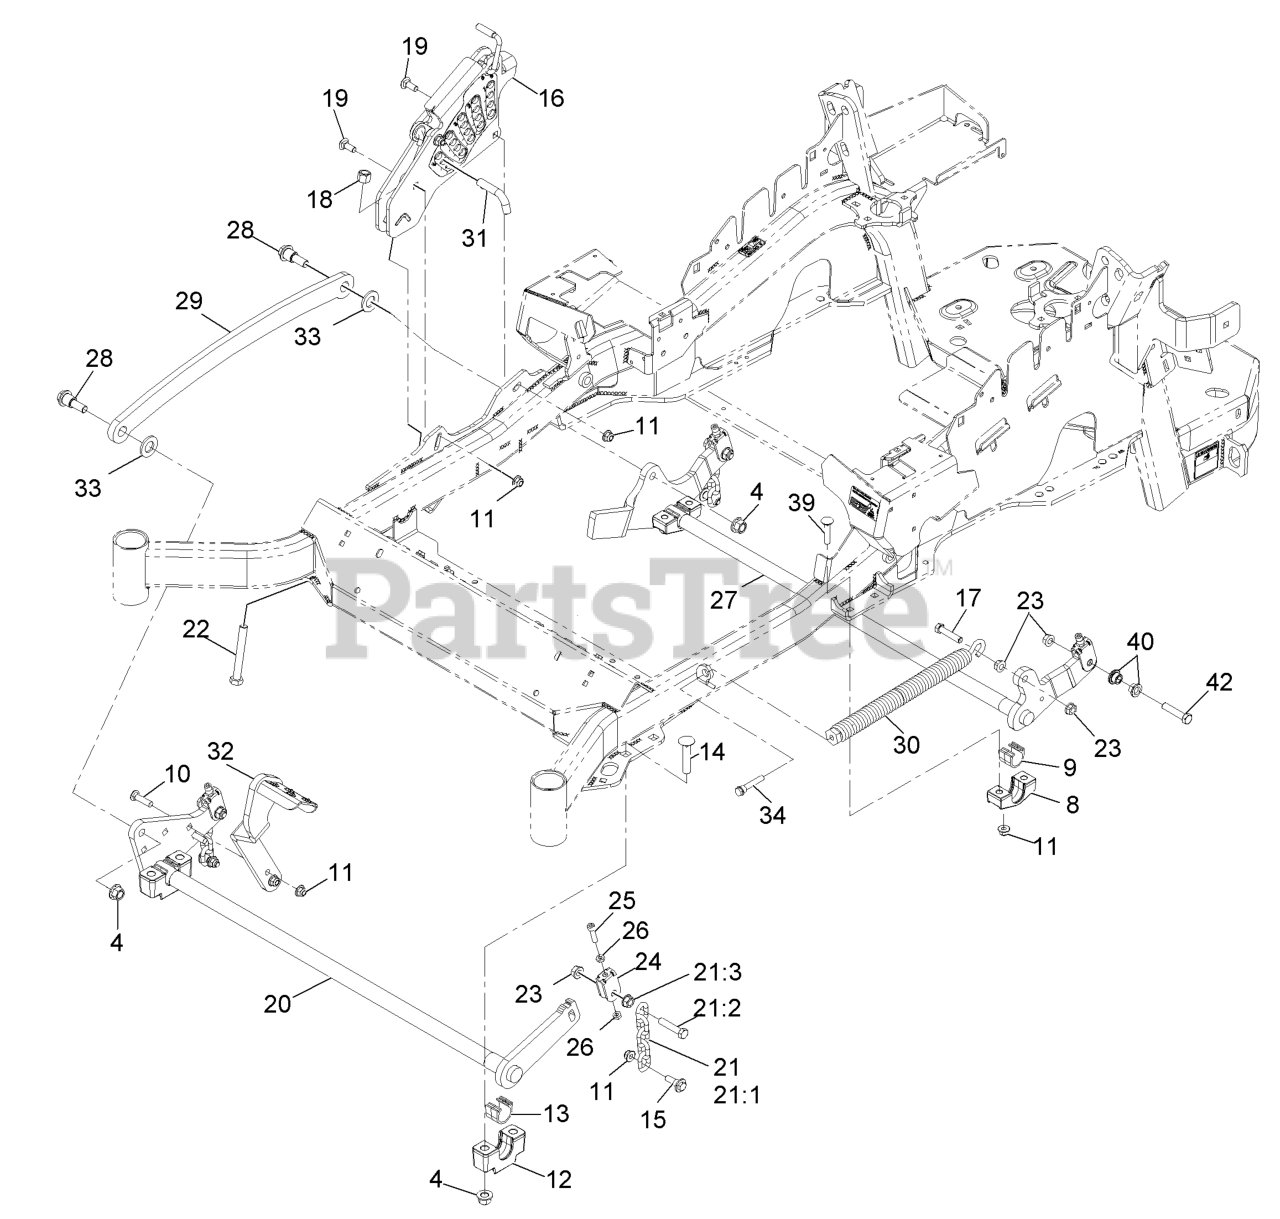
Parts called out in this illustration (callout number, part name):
4	Nut-Lock 1/2-13
9	BEARING-CROSS SHAFT, REAR
10	SCREW-CARR
11	NUT-HF, NI
12	SUPPORT-CROSS SHAFT, BEARING
13	BEARING-CROSS SHAFT, FRON
14	Bolt-Carriage 1/2-13 X 2 1/2 Spl Neck
15	SCREW-SHOULDER, HHF
16	HOC ASM
17	SCREW-HH
18	NUT-LOCK, NI
19	BOLT-CARR
21	DECK LIFT CHAIN ASM
21:1	CHAIN-LIFT, DECK
21:2	SCREW-HH
22	BOLT-TAP
24	YOKE-ADJUST, DECK
25	SCREW-HH
26	NUT-JAM
27	LIFT-DECK, REAR
28	SCREW-SHOULDER, HHF 1/2-13 X 1.12
29	LINK-LIFT, DECK
30	SPRING-EXTENSION
31	PIN-HOC
32	LEVER-FOOT
33	WASHER-FLAT
34	BOLT-SHOULDER
39	SCREW-CARR
40	BUSHING-FLANGED
42	SCREW-HH
